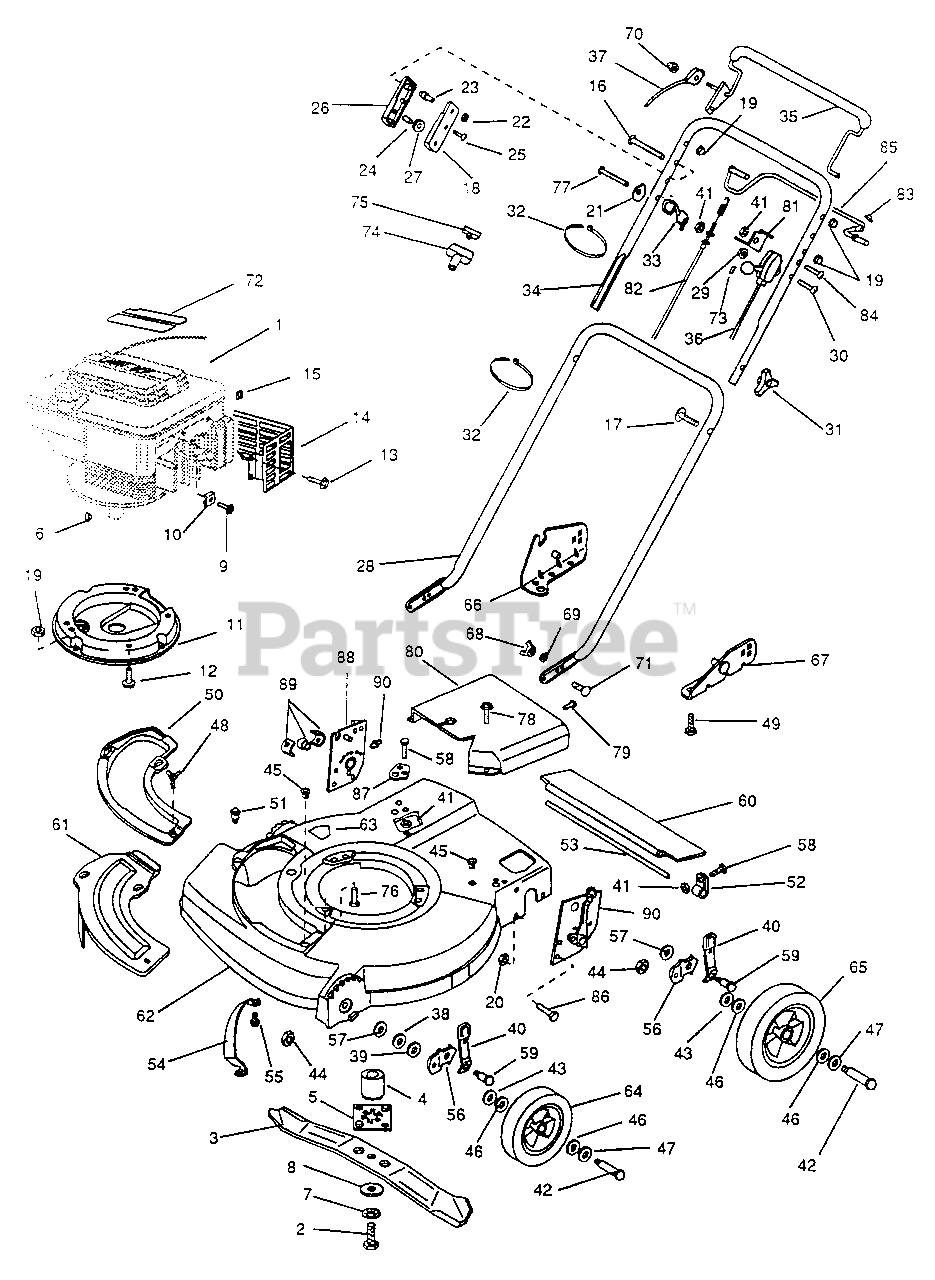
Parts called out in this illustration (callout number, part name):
2	Bolt-Blade
3	Blade-21"
4	Hub-Blade Driver
5	Plate-Blade Driver
6	Key, Woodruff (Push)
7	Lock Washer
8	Washer
9	Screw, Hex Hd.
10	Clamp
11	Plate-Engine Mounting
12	Screw-Thread Forming
13	Screw-Hex Washer Hd.
14	Shield Assembly-Muffler
15	Clip-Wire Retainer
16	Screw
17	Screw
18	Case-Inner
19	Pushnut (Push)
20	Locknut (Push)
21	Washer-Curved
22	Nut, Hex Centerlock
23	Column
24	Pin
25	Screw
26	Control Case
27	Pulley
28	Handle Section-Lower
29	Locknut
30	Screw-Truss hd.
31	Knob-Handle
32	Tie Strap (Push)
33	Rope Guide
34	Handle Section-Upper
35	Control Lever Assembly
36	Cable Assembly-Throttle
37	Cable Assembly-Brake
38	Washer-Shim
39	Washer-Shim
40	Knob & Spring Ass'y (Push)
41	Locknut (Push)
42	Wheel Bolt (Push)
43	Washer (Push)
44	Nut (Push)
45	Grommet-Plastic (Push)
46	Washer-Felt (Push)
47	Washer (Push)
48	Wing Screw
49	Screw (Push)
50	Cover Plate
51	Screw-Sems
52	Clamp-Rod (Push)
53	Rod (Push)
54	Toe Bar
55	Screw
56	Bracket-Wheel (Push)
57	Washer (Push)
58	Screw
59	Shoulder Bolt (Push)
60	Trailing Shield (Push)
61	Mulch Plate
62	Housing (Inc. 63)(Push)
63	Decal-Warning
64	Wheel Ass'y (Push)
65	Wheel Ass'y-Rear (Push)
66	Bracket Assembly-R.H. (Push)
67	Bracket Assembly-L.H. (Push)
68	Wing Nut
69	Lock Washer
70	Acorn Nut
71	Screw-Carriage
72	Decal-Recoil
73	Decal-Throttle Control
74	Starter Handle
75	Clip-Starter Handle
76	Capscrew
77	Screw, Rope Guide
